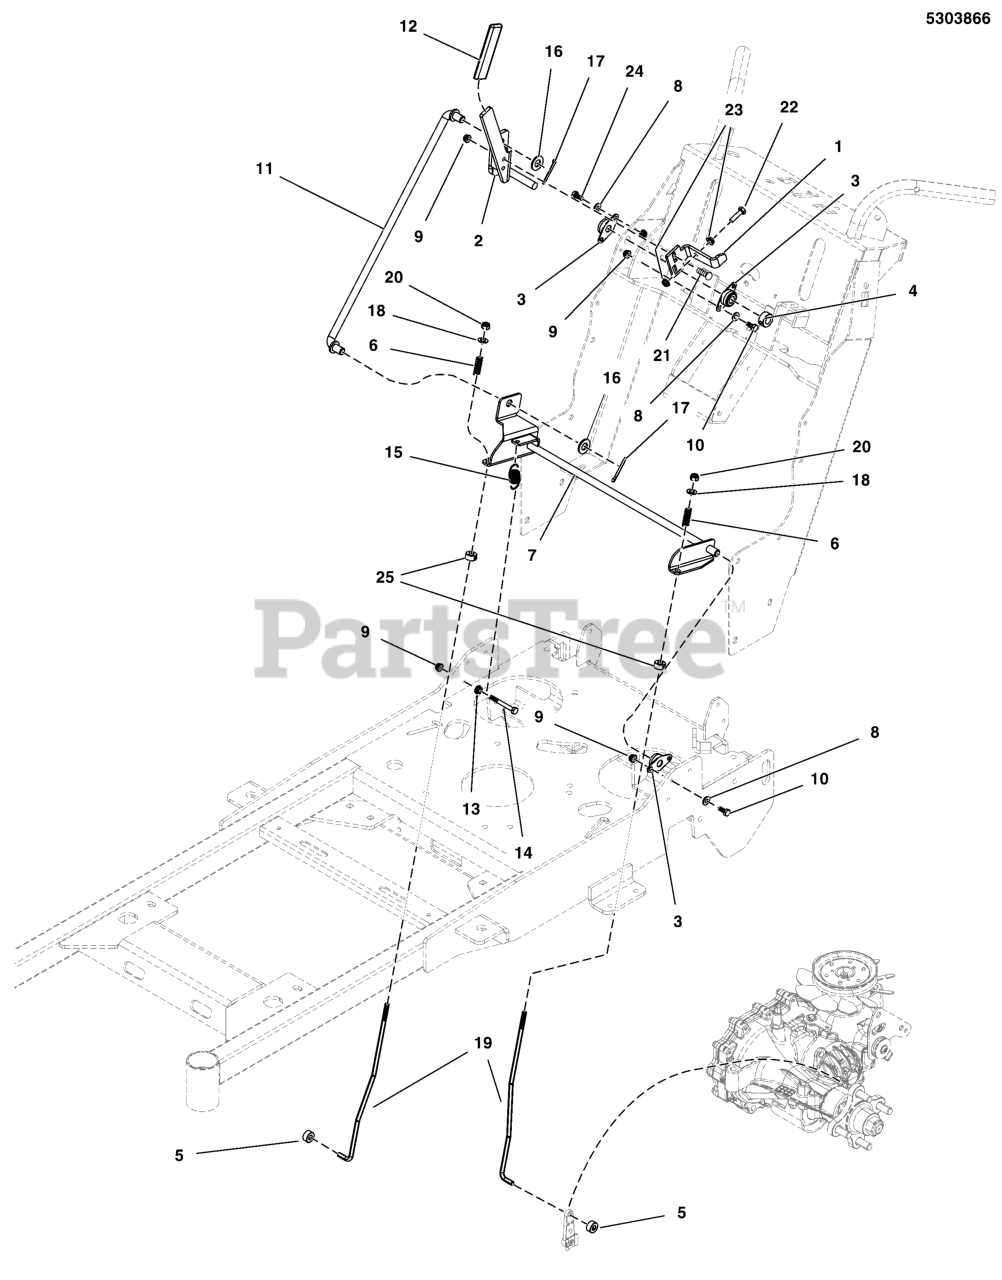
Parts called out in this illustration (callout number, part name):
1	PLATE, NEUTRAL LOCKOUT, SW25 - BLK
2	WELD, PARKING BRAKE HANDLE - BLK
3	BEARING, 1/2 FLANGED, PLASTIC BALL
4	COLLAR, 1/2 SET
5	COLLAR, 5/16 SET
6	SPRING-COMP, .375IDX2.75LGX.054WR, SS
7	WELD, PARKING BRAKE, SW25/FW25 - BLK
8	WASHER, 1/4 SAE
9	NUT, 1/4-20 HEX NYLOCK FLANGE
10	BOLT-1/4-20 X 3/4 GD5 CZ
11	ROD, PARKING BRAKE, SW25
12	GRIP, FOAM, 1/4 X 1 X 4.1
13	NUT, 1/4-20 HEX SERR. FLANGE
14	BOLT, 1/4-20 X 2-1/4 GD5 CZ
15	SPRING-EXT, .740 ODX2.025LGX.072WR, BLK
16	WASHER, 1/2 SAE
17	PIN, COTTER, 1/8 X 1-1/4
18	WASHER, 5/16" SAE
19	ROD, BRAKE CTRL, LOWER, SW25/FW25
20	NUT, 5/16-24 HEX NYLON LOCK
21	BOLT, 1/4-20X1.000,GR5,STD NECK,SQ ZC/CL
22	BOLT, 1/4-20 X 1" GD5 CZ
23	NUT, 1/4-20 HEX SERR. FLANGE
24	CREW-TRUSS HD TORX DR 1/2-20X0.750 T27
25	COLLAR, DOUBLE SPLIT, 7MM
